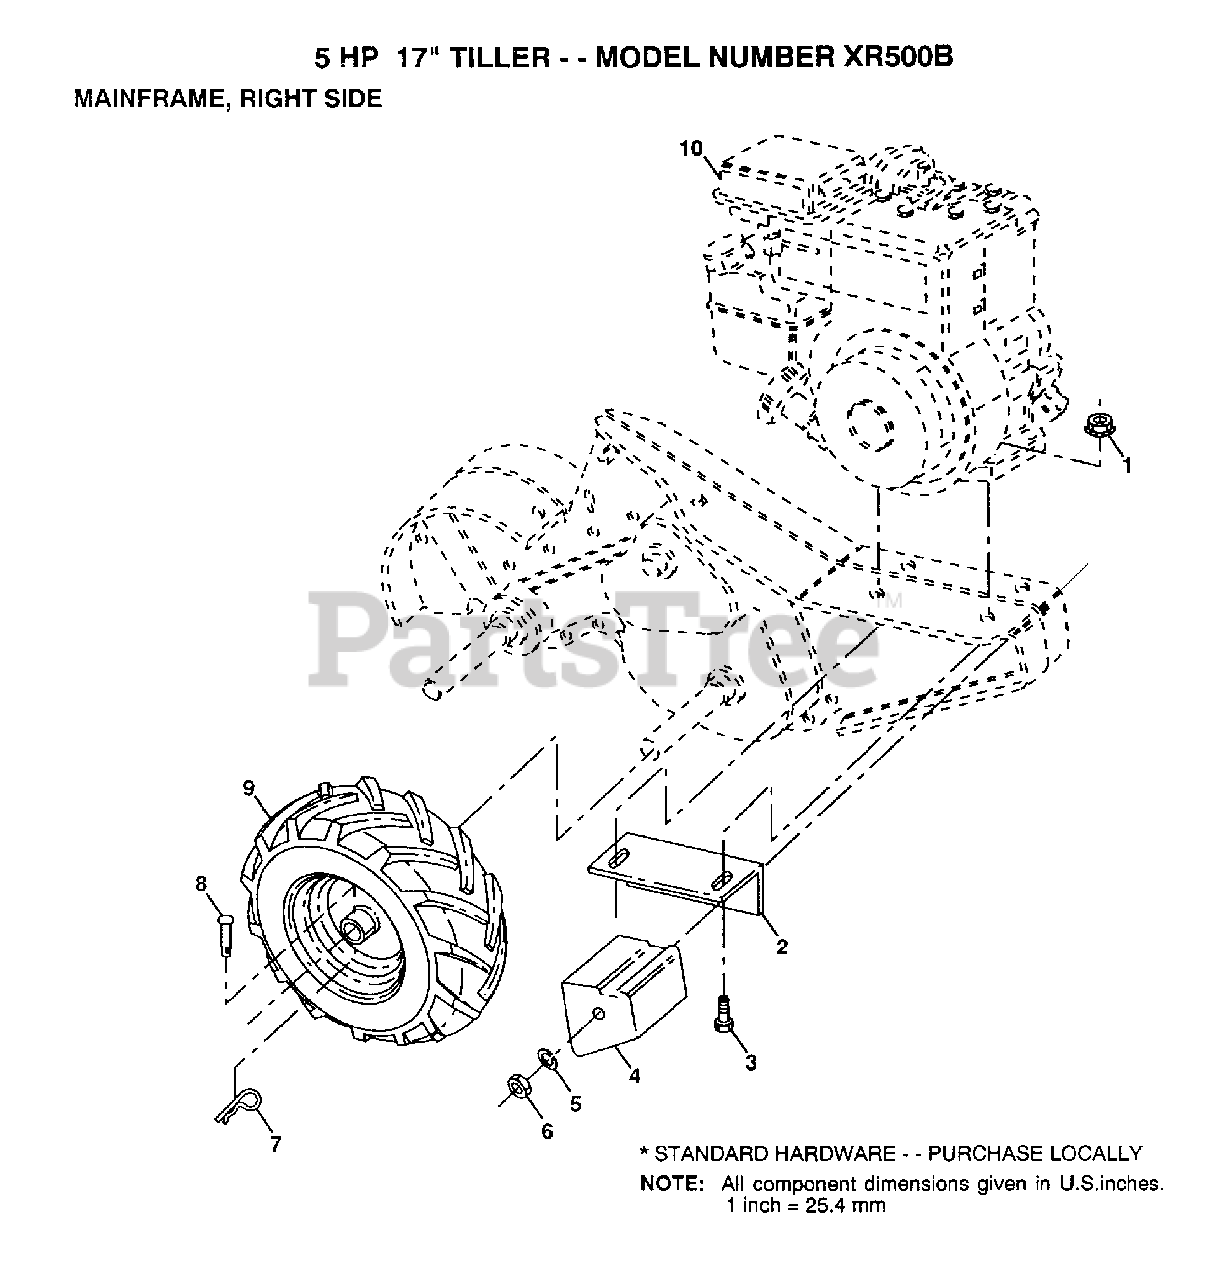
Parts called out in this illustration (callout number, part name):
2	BRACKET RH CRT
3	BOLT.HEX.5/16-1.5
4	COUNTERWEIGHT CRT
5	LOCKWASHER
6	NUT.HEX.3/8-16UNC
7	RETAINER M
8	RIVET.DRILL.1.75
9	TIRE.CHV.13X5.0-6
